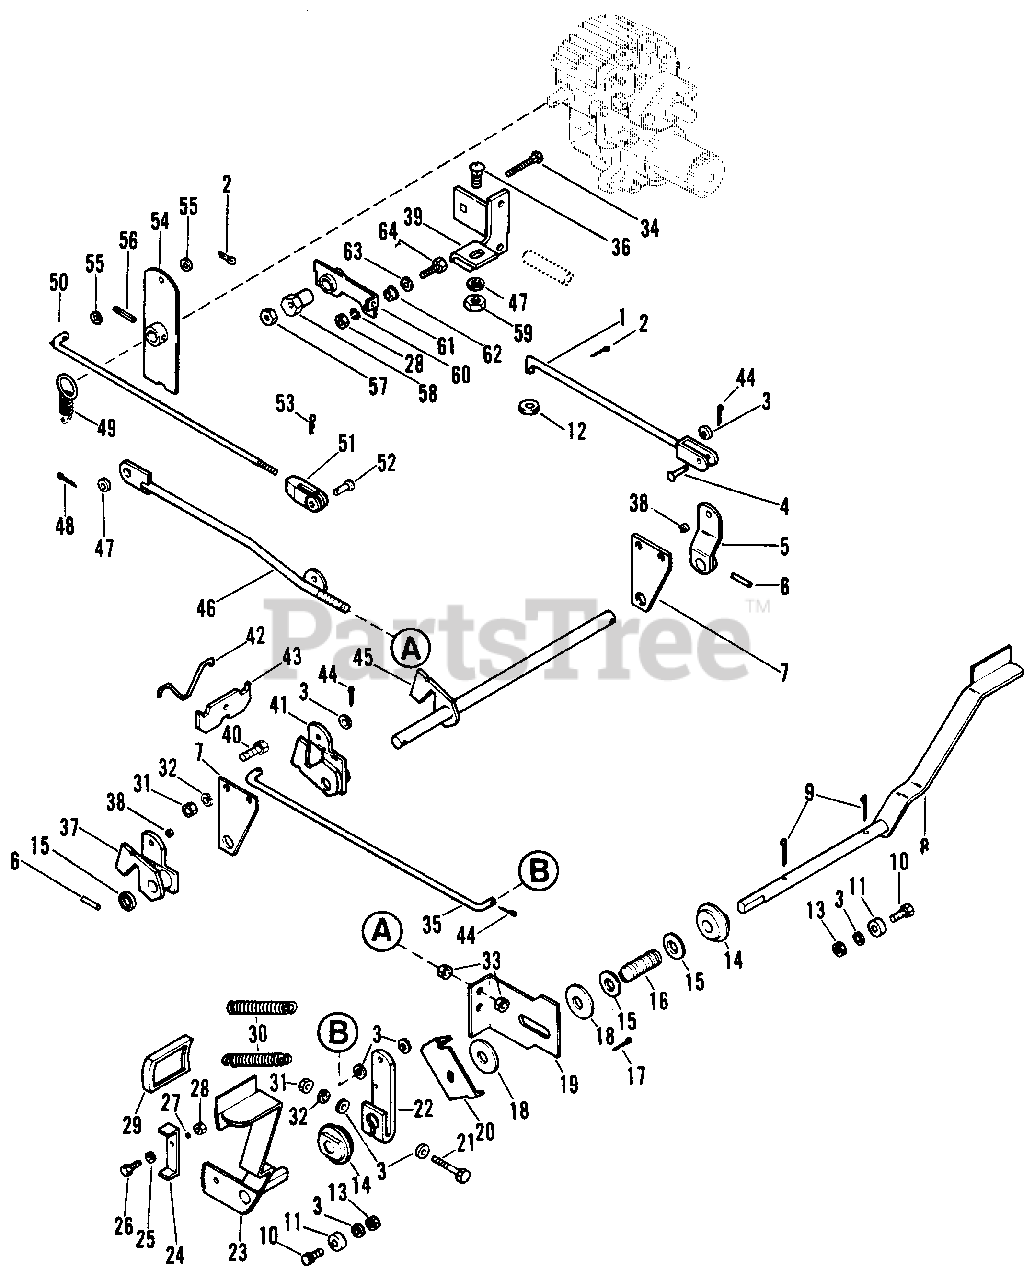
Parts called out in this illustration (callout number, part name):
1	Brake Rod
2	Pin, Cotter .09 x .75
3	Washer, Flat .406 x .812 x .065
4	Clevis Pin
5	Brake Arm
6	Pin, Groove
7	Plate
8	L.H. Lever
9	Pin, Cotter .187 x 1.25
10	Bolt, Hex 5/16-18 x .875
11	Spacer
12	Washer, .380/.385 x .812 x 24 Ga.
13	Nut, Lock 5/16-18
14	Bushing, Flange .75 x 1.75 x .75
15	Washer, Flat .813 x 1.37 x .100
16	Spring, Comp. 2-17/32 Free Length
17	Pin, Cotter .09 x 1.00
18	Washer, .751/.757 x 2.000 x .125
19	Neutralizer Plate
20	Neutralizer Arm
21	Bolt, Hex 3/8-16 x 2.25
22	Arm, Brake
23	R.H. Lever
24	Brake Latch
25	Washer, Flat .281 x .625 x .065
26	Bolt, Hex 1/4-20 x .875
27	Spacer Bushing
28	Nut, Lock 1/4-20
29	Pedal Pad
30	Spring, Extension 3-1/2 Free Length
31	Nut, Hex 3/8-16
32	Washer, Lock 3/8 Reg.
33	Nut, Lock 1/2-13
34	Bolt, Carriage 5/16-18 x 2.25
35	Brake Rod
36	Bolt, Carriage 1/2-13 x 1.25
37	Brake Arm
38	Grommet
39	Mount Weldment
40	Bolt, 3/8-16 x 1.00 Rd Hd Sq Nk
41	Arm
42	Clip
43	Balance Link
44	Pin, Cotter .125 x .75
45	Brake Shaft
46	Neutralizer Rod
47	Washer, Flat .500 x 1.250 x .083
48	Pin, Cotter .125 x 1.00
49	Spring, Ext. 2-13/16 Free Length
50	Shift Rod
51	Yoke
52	Clevis Pin
53	Hairpin, Internal 3/32 x 1-3/16
54	Shift Arm
55	Washer, Flat .312 x .734 x .065
56	Pin, Roll 1/4 x 1-3/8
57	Nut, Lock 5/16-18
58	Eccentric
59	Nut, Lock 1/2-13
60	Washer, Lock Ext. 1/4 I.D. Hi-Collar
61	Detent Arm
62	Ball Bearing, 1/4 I.D.
63	Washer, .281 x 1.25 x .062
64	Bolt, Hex 1/4-20 x 1.00
